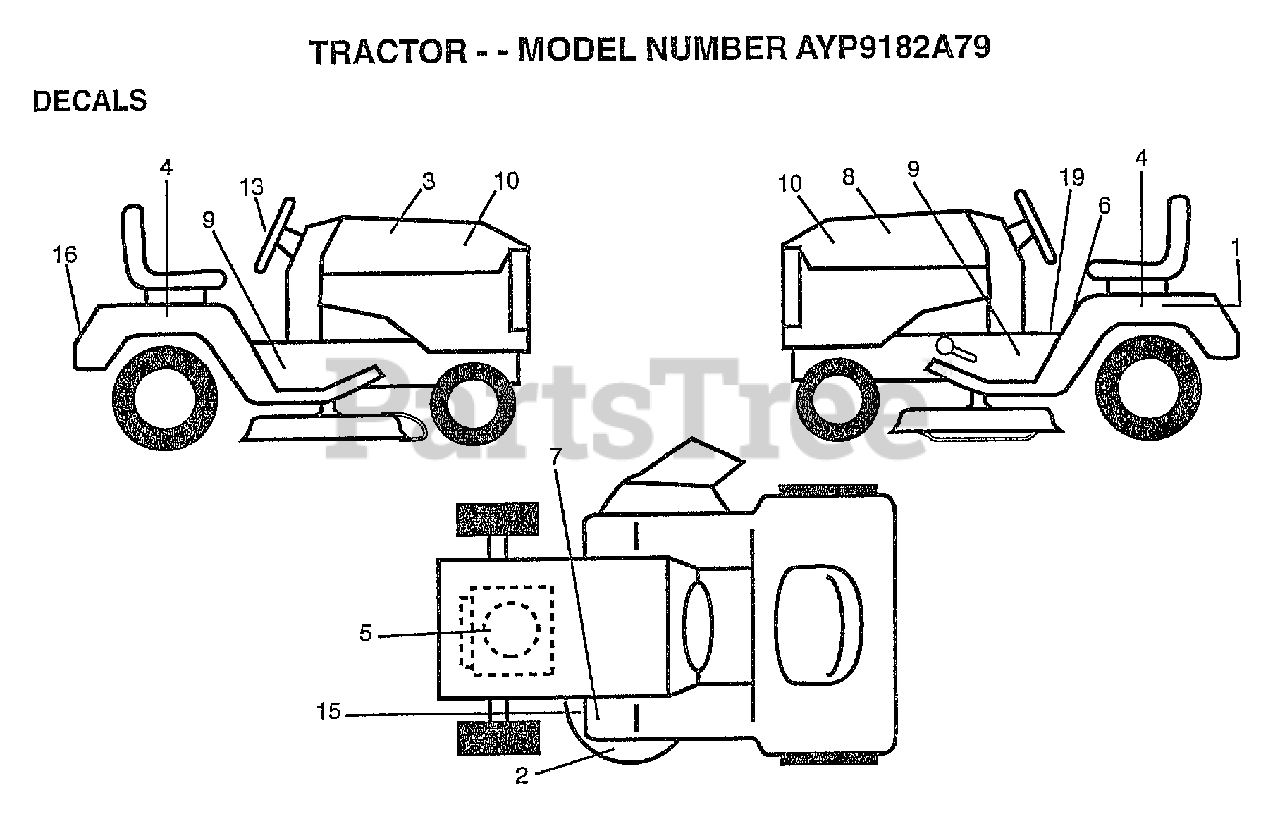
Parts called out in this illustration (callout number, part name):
1	DECAL.BATRY.3-3908
2	DECAL DECK WIZ +
3	DECAL.HD.RH.WIZAR
4	DECAL.FENDER.WIZ
5	DECAL, HP, ENGINE
6	"DECAL DANGER,FEND"
8	DECAL.HD.LH.WIZAR
9	DECAL.FENDER.WIZ
10	DECAL INSERT HOOD
13	DECAL.INS.STRG.WL
15	DECAL
19	"DECAL INST,SADDLE"
